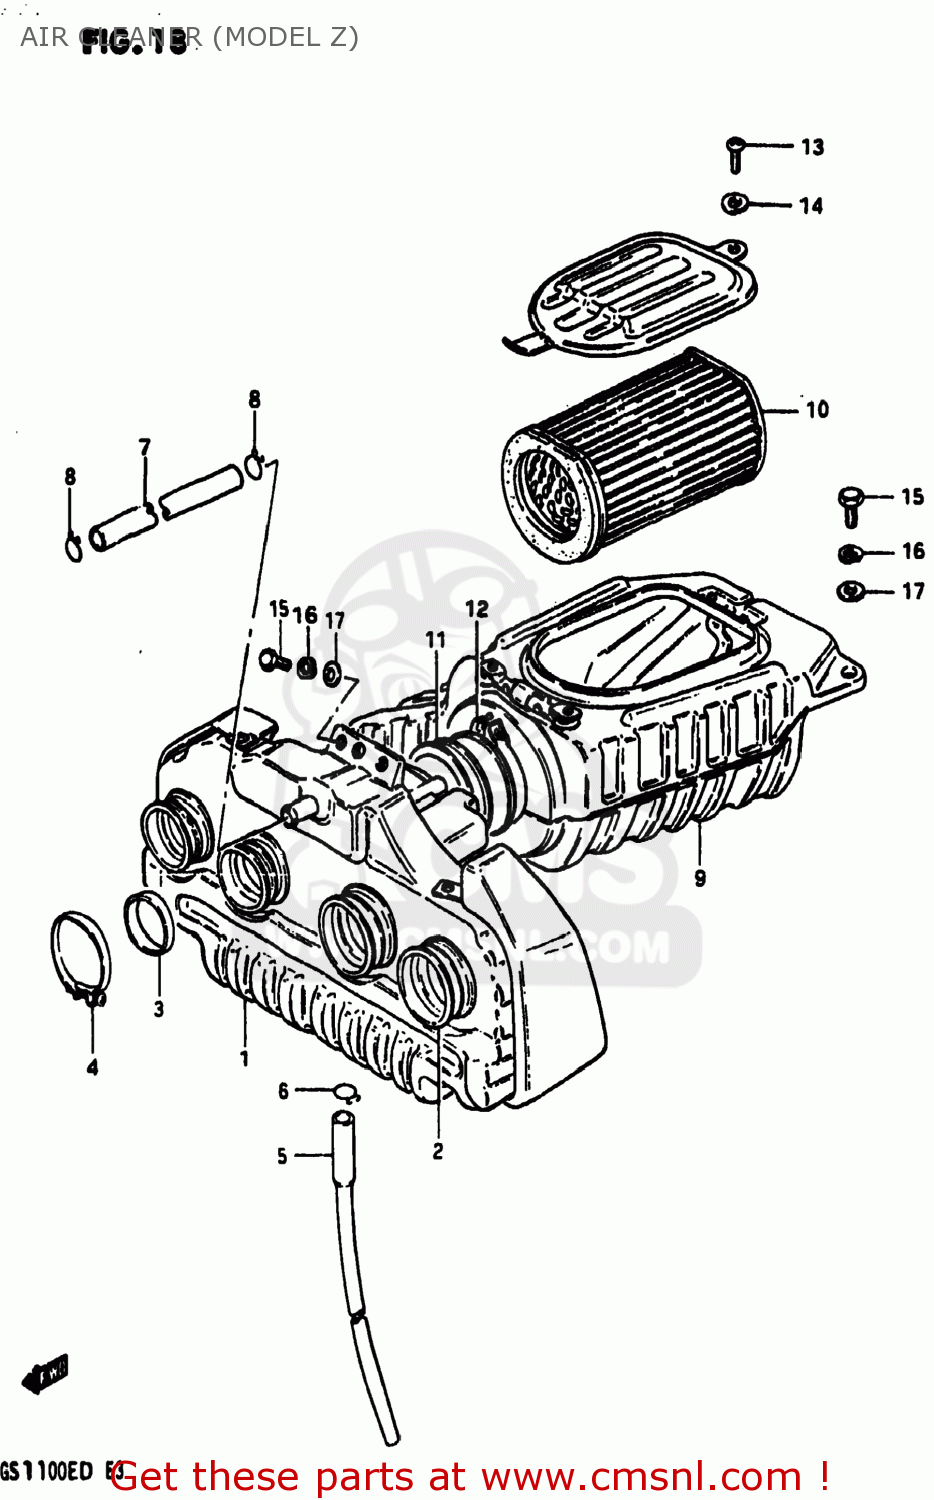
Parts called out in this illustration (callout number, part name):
1	CASE COMP,AIR CLEANER
2	TUBE,AIR CLEANER OUTLET
3	RING,CARBURETOR AIR INLET HOSE
4	CLAMP
5	DRAIN TUBE
6	CLIP
7	TUBE,BREATHER
8	CLIP
9	CLEANER SET,AIR,REAR
10	FILTER,AIR CLEANER
11	HOSE,AIR CLEANER
12	BAND
13	SCREW
14	LOCK WASHER
15	BOLT
16	LOCK WASHER
17	WASHER
